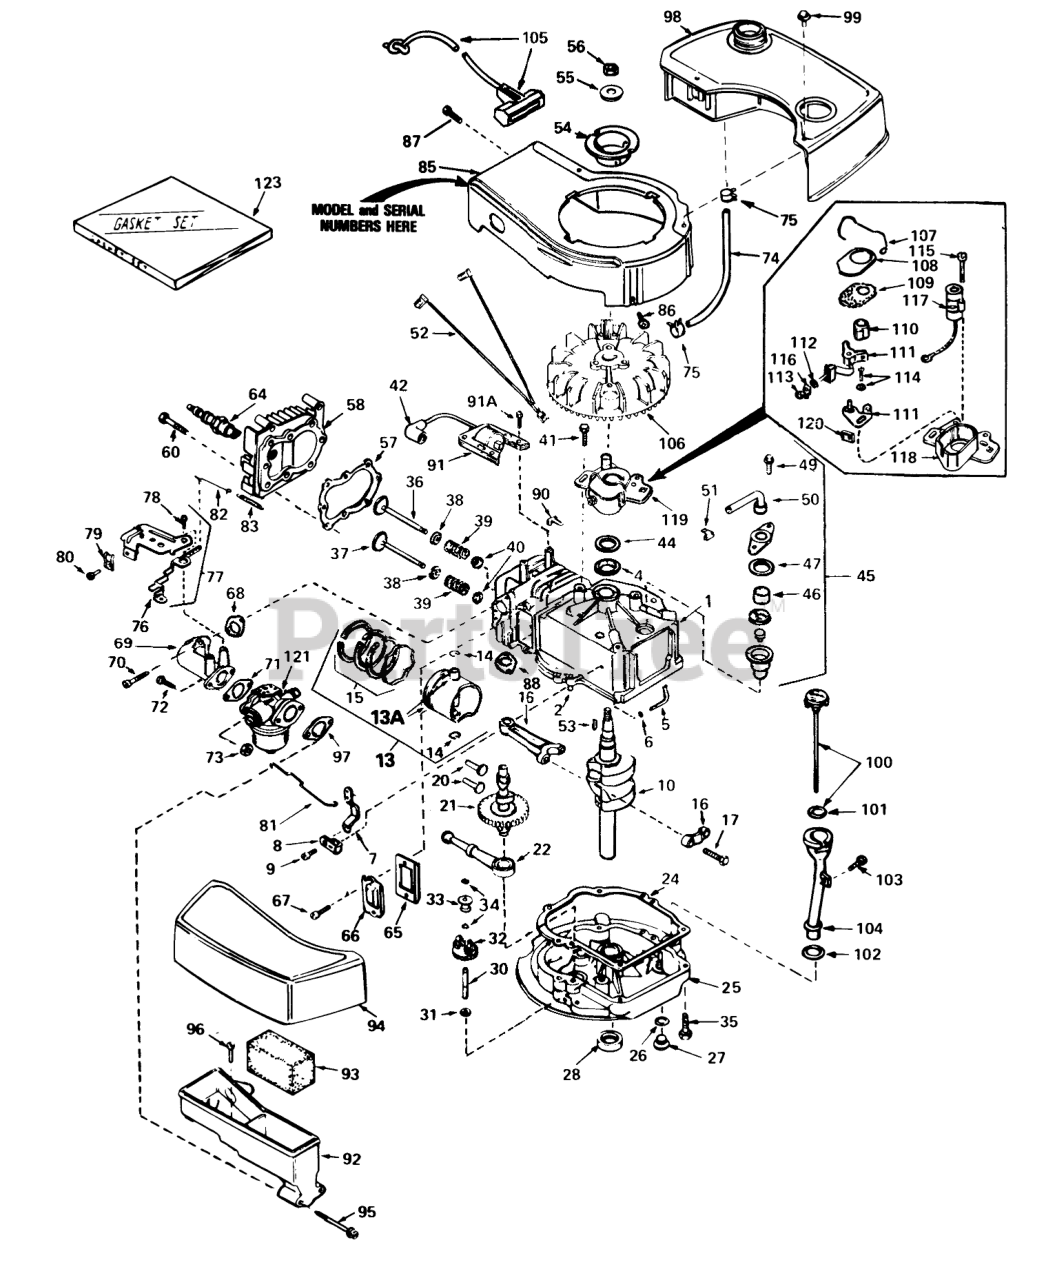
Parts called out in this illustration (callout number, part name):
1	Cylinder Assy (Incl. #2 & 4)
2	Pin-Dowel
4	Seal-Oil
5	Rod, Governor (Incl. Ref. #6)
6	Washer-Flat
7	Governor Lever
8	Clamp-Lever, Governor
9	Screw
10	Crankshaft
13	Piston, Pin & Ring Assy. (Incl. Ref. #13A, 14 & 15)(Std.)
13	Piston, Pin & Ring Assy. (Incl. Ref. #13A, 14& 15) (.010 Oversize)
13	Piston, Pin & Ring Assy. (Incl. Ref. #13A, 14& 15) (.020 Oversize)
13A	Piston & Pin Assy. (Incl. Ref. #14)(Std.)
13A	Piston & Pin Assy. (Incl. Ref. #14)(.010 Oversize)
13A	Piston & Pin Assy. (Incl. Ref. #14)(.020 Oversize)
14	Ring-Retaining, Piston Pin
15	Ring Set Piston (Std.)
15	Ring Set Piston (.010 Oversize)
15	Ring Set Piston (.020 Oversize)
16	Connecting Rod (Incl. 46)
17	Bolt-Rod, Connecting
20	Lifter-Valve
21	Camshaft(Mech.Comp. Release)
22	Oil Pump ASM
24	Gasket, Mounting
25	Flange Assy., Mounting (Incl. Ref. #26 thru 30)
26	Gasket-Oil Drain
27	Plug Oil Drain
28	Seal Oil
30	Shaft-Governor
31	Washer-Flat
32	Gear Assy., Gov. (Incl. Ref. #31)
33	Spool-Governor
34	Ring-Retaining
35	Screw (1/4-20 x 1-1/4)
36	Valve Intake (Std.)(Incl. #38, 39 & 40)
36	Valve, Intake (1/32" Oversize)(Incl. Ref. #38, 39 & 40)
37	Valve, Exhaust (Std.)(Incl. Ref. #38, 39 & 40)
37	Valve, Exhaust (1/32" Oversize)(Incl. Ref. #38, 39 & 40)
38	Cap-Upper Valve Spring
39	Spring-Valve
40	Cap-Valve, Spring
42	Cover-Spark Plug
44	Gasket Stator
45	Breather Assy. (Incl. Ref. #46, 47, 49, 50 & 51)
46	Element-Breather
47	Gasket-Breather
49	Screw (10-24 x 9/16)
50	Tube, Breaker
51	Clip, Breather
52	Wire Ground
53	682488 LB GRASS HI-
54	Hub-Starter
55	Washer-Belleville
56	Nut-Flywheel
57	63573 GIL 42 SNWTHW
58	Dipper-Oil
60	Screw (5/16-18x1-1/2)
64	Plug, Spark (J17LM or equiv.)
64	Plug, Spark (Champion RCJ-8)
65	Gasket-Breather
66	Cover-Valve
68	Gasket-Intake
69	Pipe, Intake (Incl. Ref. #68)
70	Screw (1/4-20 x 1)
71	Gasket-Carburetor
72	Screw (1/4-28 x 7/8)
73	Nut and Lock Washer (1/4-28)
74	Line-Fuel
75	Clamp-Line, Fuel
76	Lever Control
77	Control Assy., Speed (Incl. Ref. #76 & 78)
78	Screw, Hex Washer Hd Shoulder Self-Tap
79	Conduit
80	Screw (10-32 x 3/8)
81	Link-Throttle
82	Link Governor Spring
83	Spring Governor
85	Housing Blower
86	Screw
87	Screw (10-24 x 9/16)
88	Gasket Exhaust
90	Clip-Wire
91	Lamination
91A	Screw
92	Body Air Cleaner
93	Filer, Air
94	Cove, Air Cleaner
95	Screw Fil Hd.
96	Screw, Hex Hd.
97	Gasket-Air Cleaner
98	Tank, Fuel
99	Screw (10-32 x 35/64)
100	Dipstick, OiI (Incl. Ref. #101)(Twist Lock)
103	Screw (10-32 x 1/2)
104	Tube-Oil Fill
105	Rope Assy., Starter
106	FIywheel
107	Spring Breaker Box
108	Cover-Dust
109	Gasket-Dust Cover
110	Cam-Breaker
111	Breaker Assy.
114	Breaker Screw
115	Condenser Screw
116	Terminal, Ground
117	Condenser
118	Stator Plate
119	Stator Assy. (Incl. Ref. #107, 111 thru 118 & 120)
120	Felt,Cam Wiper
121	Carburetor (Incl. Ref. #71)
123	Gasket Set
